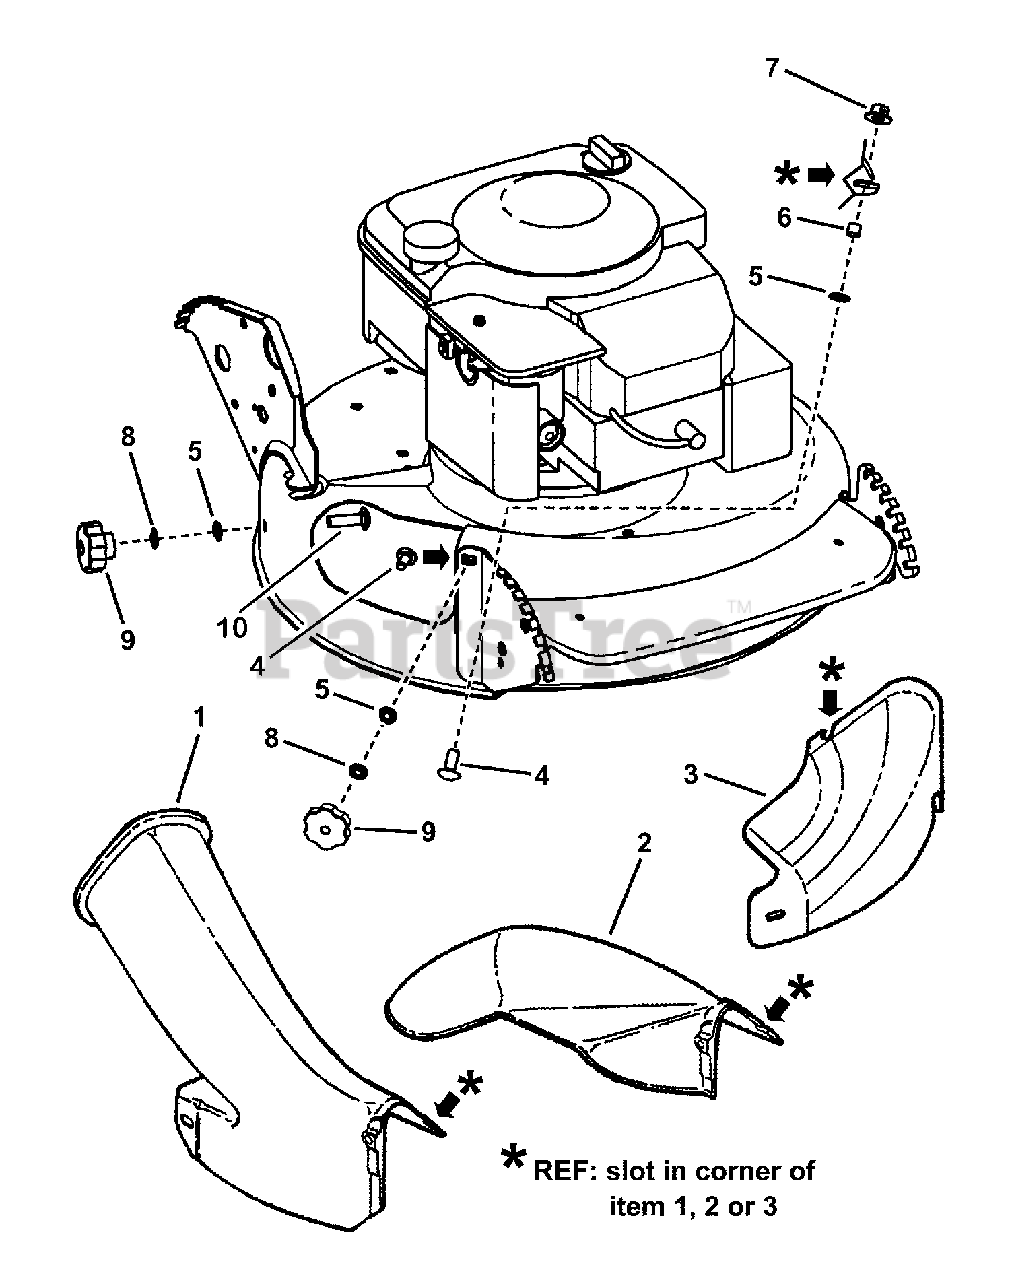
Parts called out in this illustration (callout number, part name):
1	ADAPTER, Grass Bag
2	CHUTE, 21" Side
3	COVER, 21" Deck
4	BOLT, 5/16-18 x 1-1/8" Short Neck Carriage GR 5 ZP
5	RETAINER, 5/16" Bolt
6	SPACER, .316 I.D. x .375 O.D. x .310 thick
7	NUT, 5/16-18 Hex Large Flange Center Lock
8	WASHER, 5/16" Internal/External Tooth Lock
9	KNOB, Fluted, 5/16-18 x 1/2"
10	BOLT, 5/16-18 x 3/4" Short Neck Carriage GR 5
